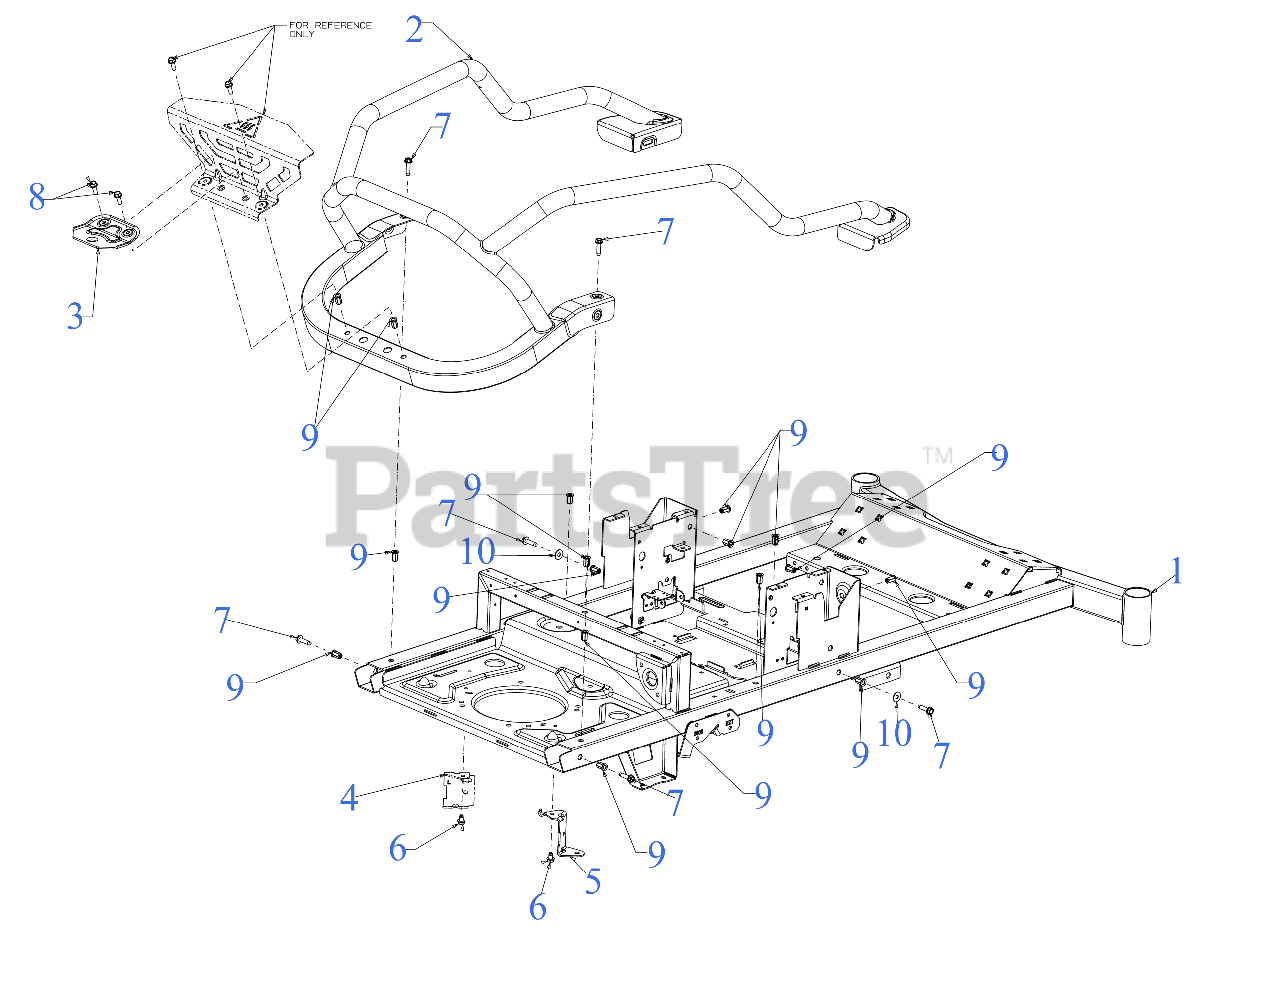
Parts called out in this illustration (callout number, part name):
1	FRAME
2	UPPER FRAME
3	HITCH PLATE
4	TRANSMISSON MOUNT SUPPORT (LH)
5	TRANSMISSON MOUNT SUPPORT (RH)
6	SCREW 5/16-18 x .500
7	SCREW 5/16-18 x 1.25
8	SCREW 5/16-18 x .875 GR5
9	NUT RIVET 5/16-18 LOCK
10	FLAT WASHER
